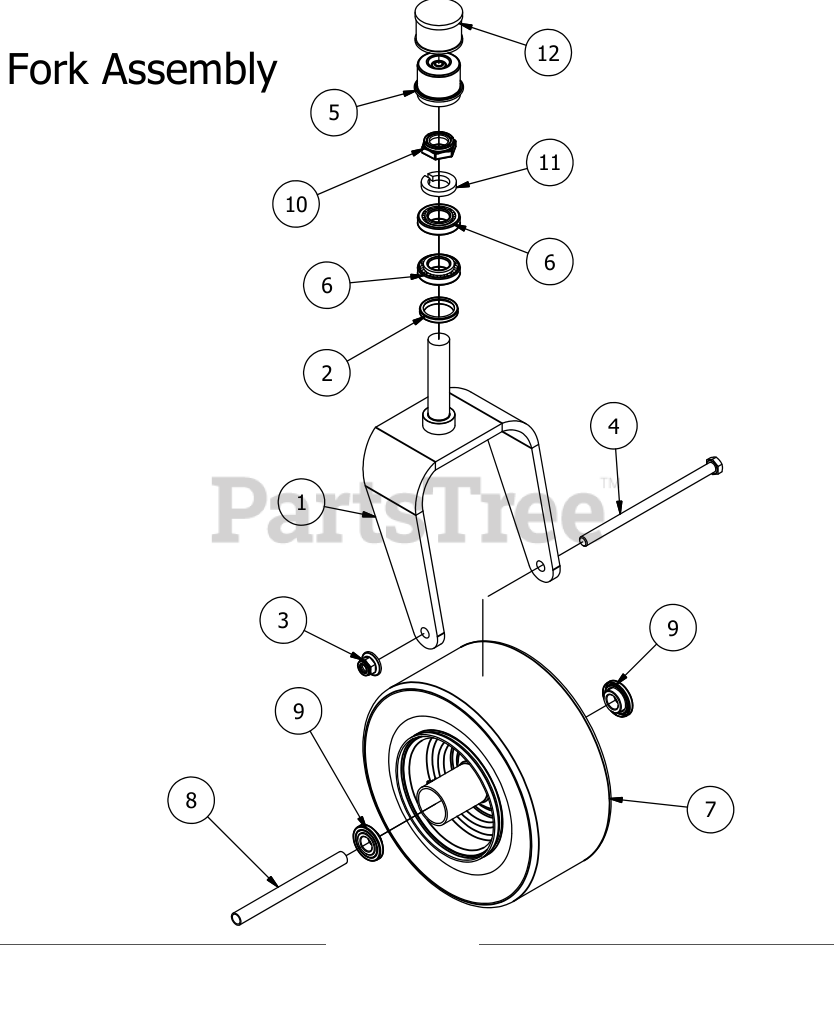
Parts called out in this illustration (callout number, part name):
1	Front Fork
3	1/2-13 Nylon Flange Nut
4	1/2" x 9" GR 5 Hex Bolt
5	Dust Cover
7	Tire and wheel assembly
8	Front Wheel Spanner
9	1 3/8" Wheel Bearing
10	1" Fine Thread 1/2 Nylock Nut
11	1" Lock Washer
12	Spring Cap Cover
